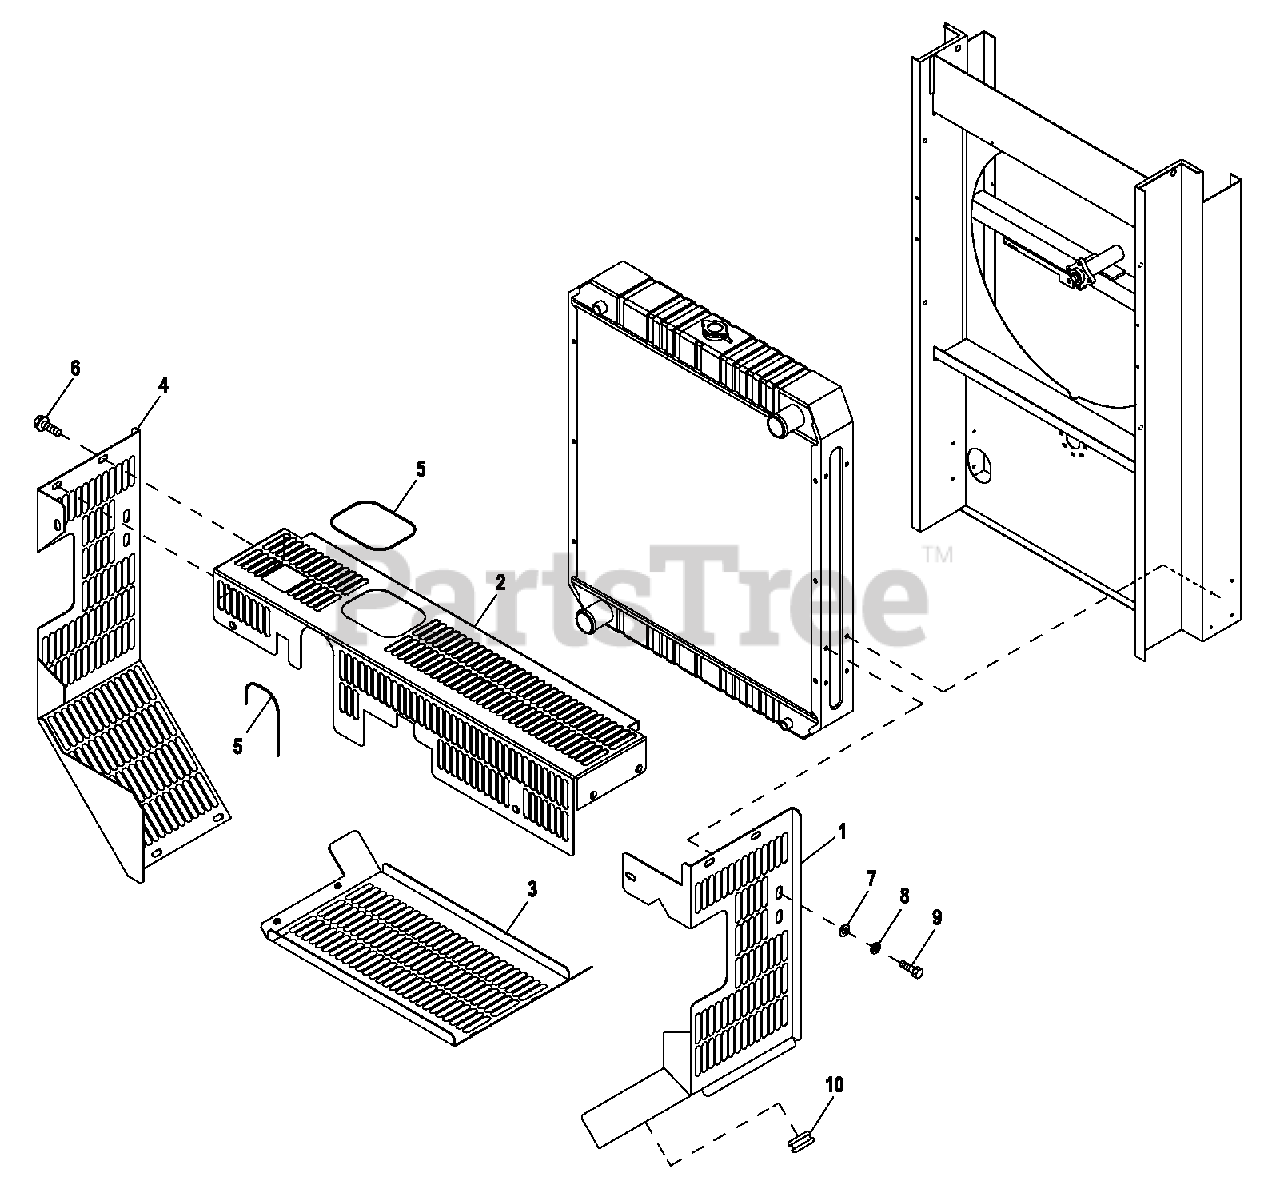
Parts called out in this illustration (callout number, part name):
1	GUARD BELT RIGHT HAND C5
2	GUARD, BELT TOP C5
3	GUARD BELT BOTTOM C5
4	GUARD BELT LEFT HAND C5
5	TRIM VINYL BLACK 1/8GP (19"LG)
6	SCREW THF M6-1 X 16 N WA Z/JS
7	WASHER FLAT 3/8-M10 ZINC
8	WASHER LOC KM10
9	SCREW HHC M10-1.5 X 20 G8.8
10	GROMMET 1.25 X .25 X 1.00
